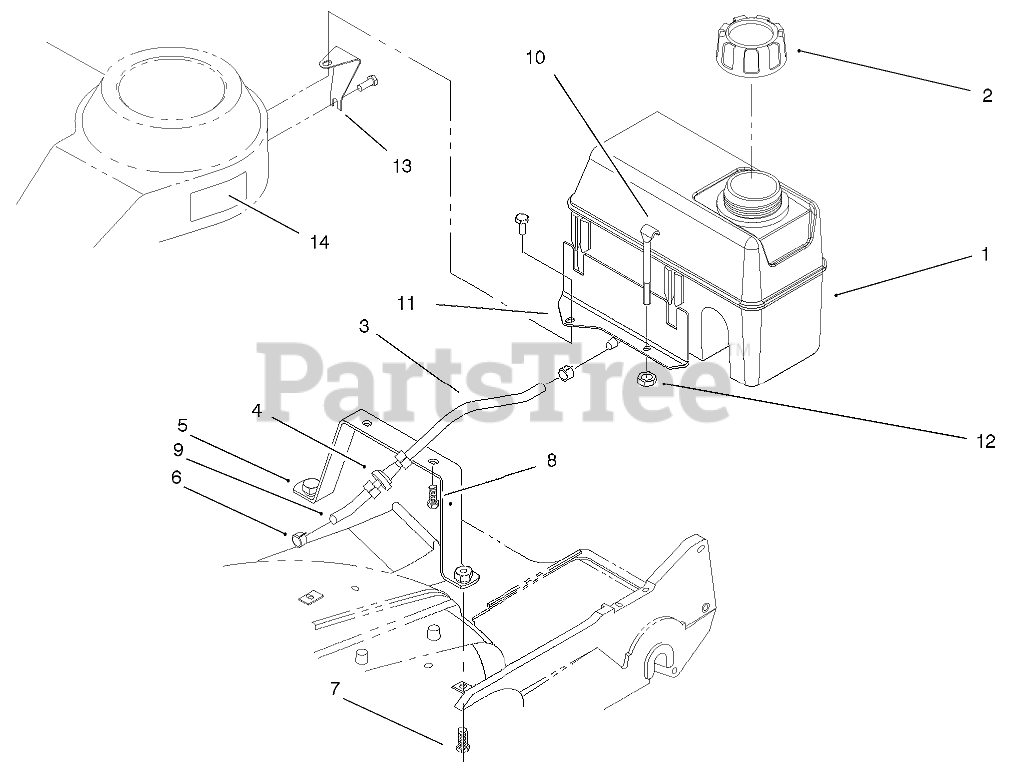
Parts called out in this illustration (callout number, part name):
1	TANK-GAS
2	GAS CAP ASM
3	HOSE-FUEL
4	FILTER-FUEL
5	BASE-TANK
6	CLAMP-FUEL LINE
7	SCREW-TAPTITE
8	SCREW-HWH
9	LINE-GAS
10	RETAINER - FUEL TANK
11	BRACKET-TANK
12	NUT-LOCK, NI
13	SUPPORT-TANK BRACKET
14	DECAL-FUEL, 2 CYCLE
